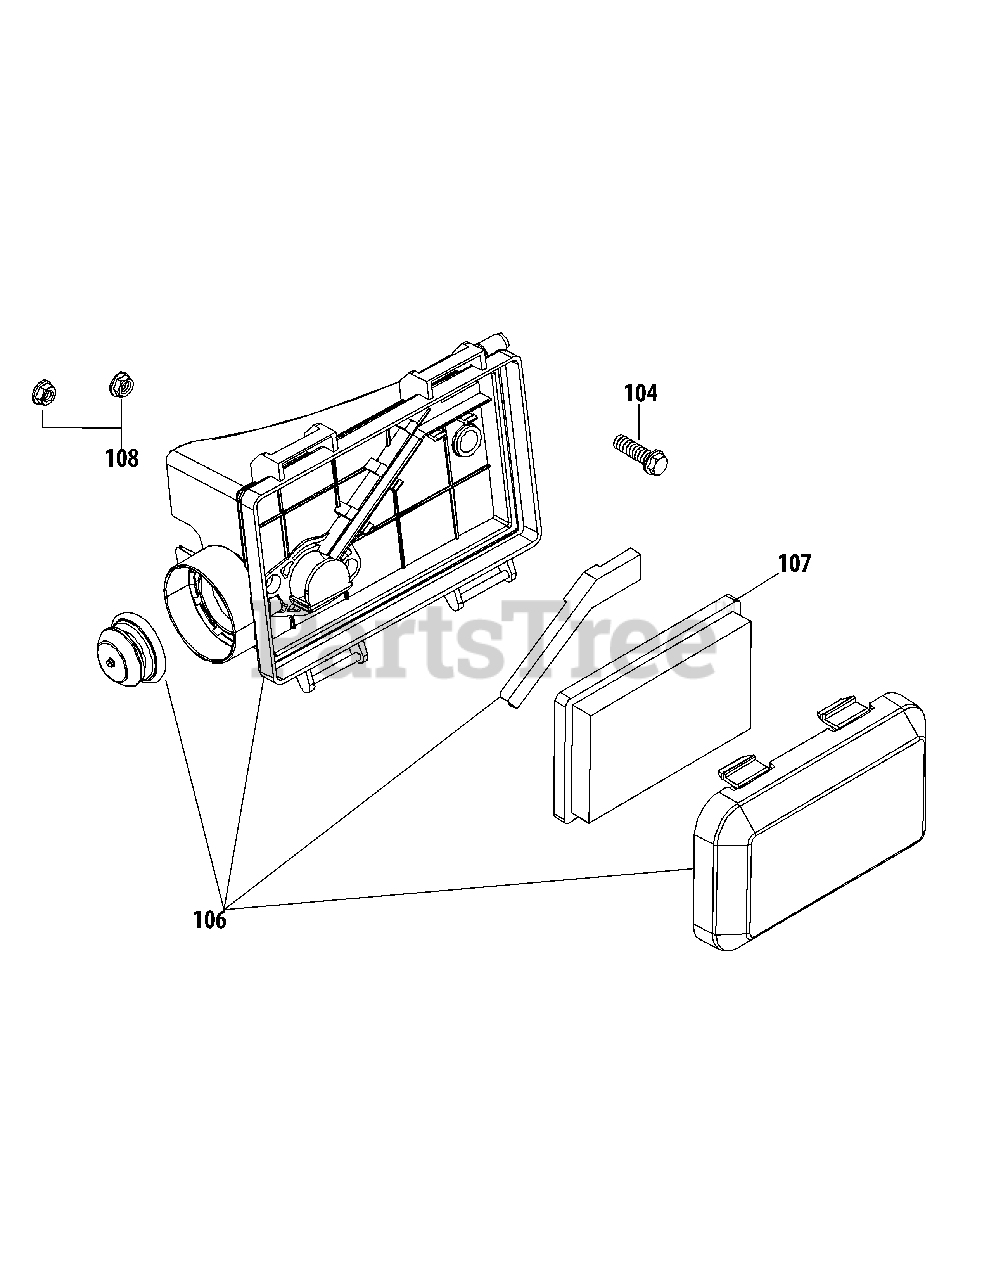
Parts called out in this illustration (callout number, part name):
104	Bolt M6X30 Af Base/Coil/E-Starter
106	Air Filter Cover
107	Air Filter Element, Paper
108	Nut M6X10Mm Starter/Carb/Muff
